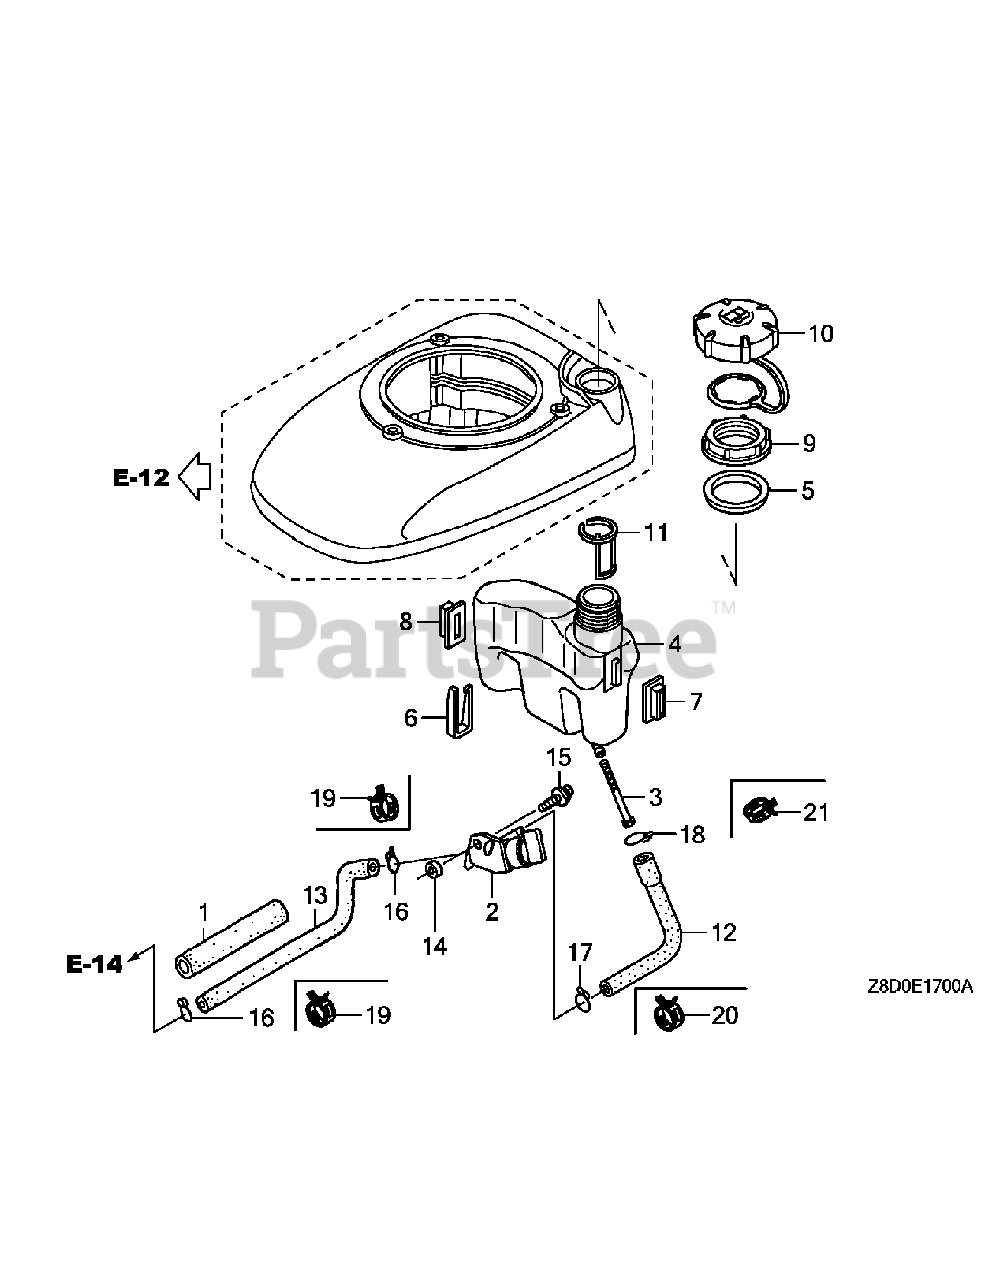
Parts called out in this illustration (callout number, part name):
1	Supporter Rubber, 107mm
2	Fuel Cock Assembly
3	Fuel Strainer
5	Fuel Filler Neck Seal
6	Tank Mounting Clip
7	Tank Mounting Rubber A
8	Tank Mounting Rubber B
9	Tank Mounting Nut
10	Fuel Tank Cap Assembly
11	Fuel Level Gauge
12	Fuel Tank Tube
14	Fuel Cock Collar
15	Screw-Washer, 5 x 10
16	Tube Clip, B8
17	Tube Clip, B10
18	Tube Clip, C11
19	Tube Clamp, D8
20	Tube Clamp, D10
21	Tube Clamp, D12
